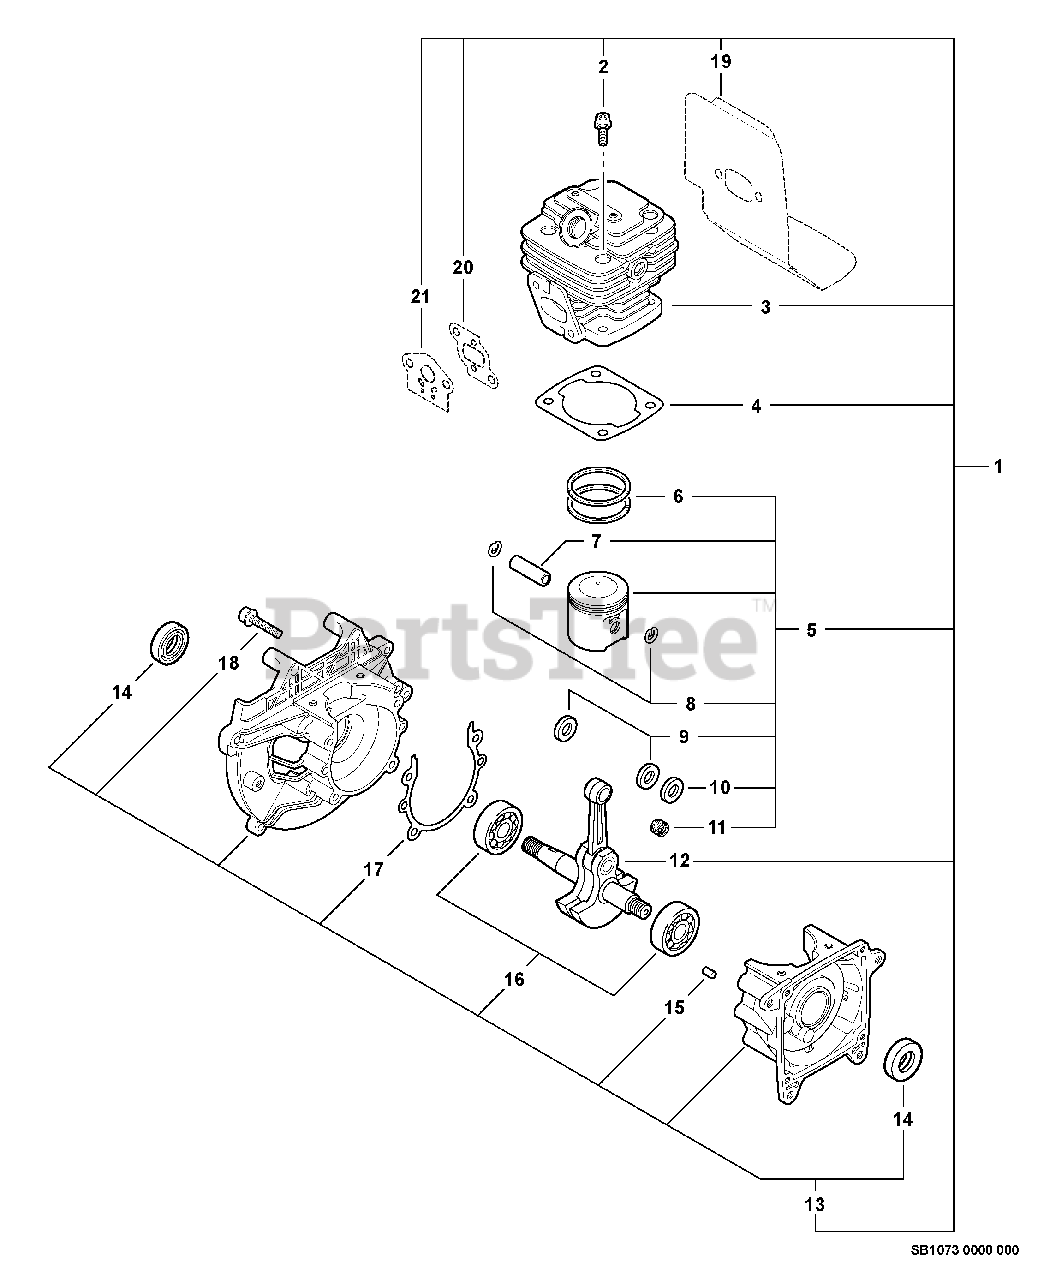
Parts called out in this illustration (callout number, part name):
1	SHORT BLOCK -- SB1073
2	SCREW - 5X20
3	CYLINDER
4	GASKET, CYLINDER
5	PISTON KIT
6	RING, PISTON
7	PIN, PISTON
8	RING, RETAINING
9	SPACER, PISTON
10	WASHER
11	BEARING, NEEDLE
12	CRANKSHAFT ASSY
13	CRANKCASE KIT
14	SEAL, OIL
15	PIN - LOCATING
16	BEARING, BALL - 6201
17	GASKET, CRANKCASE
18	SCREW - 5X30
19	SHIELD, EXHAUST
20	GASKET, INTAKE
21	GASKET, INTAKE
